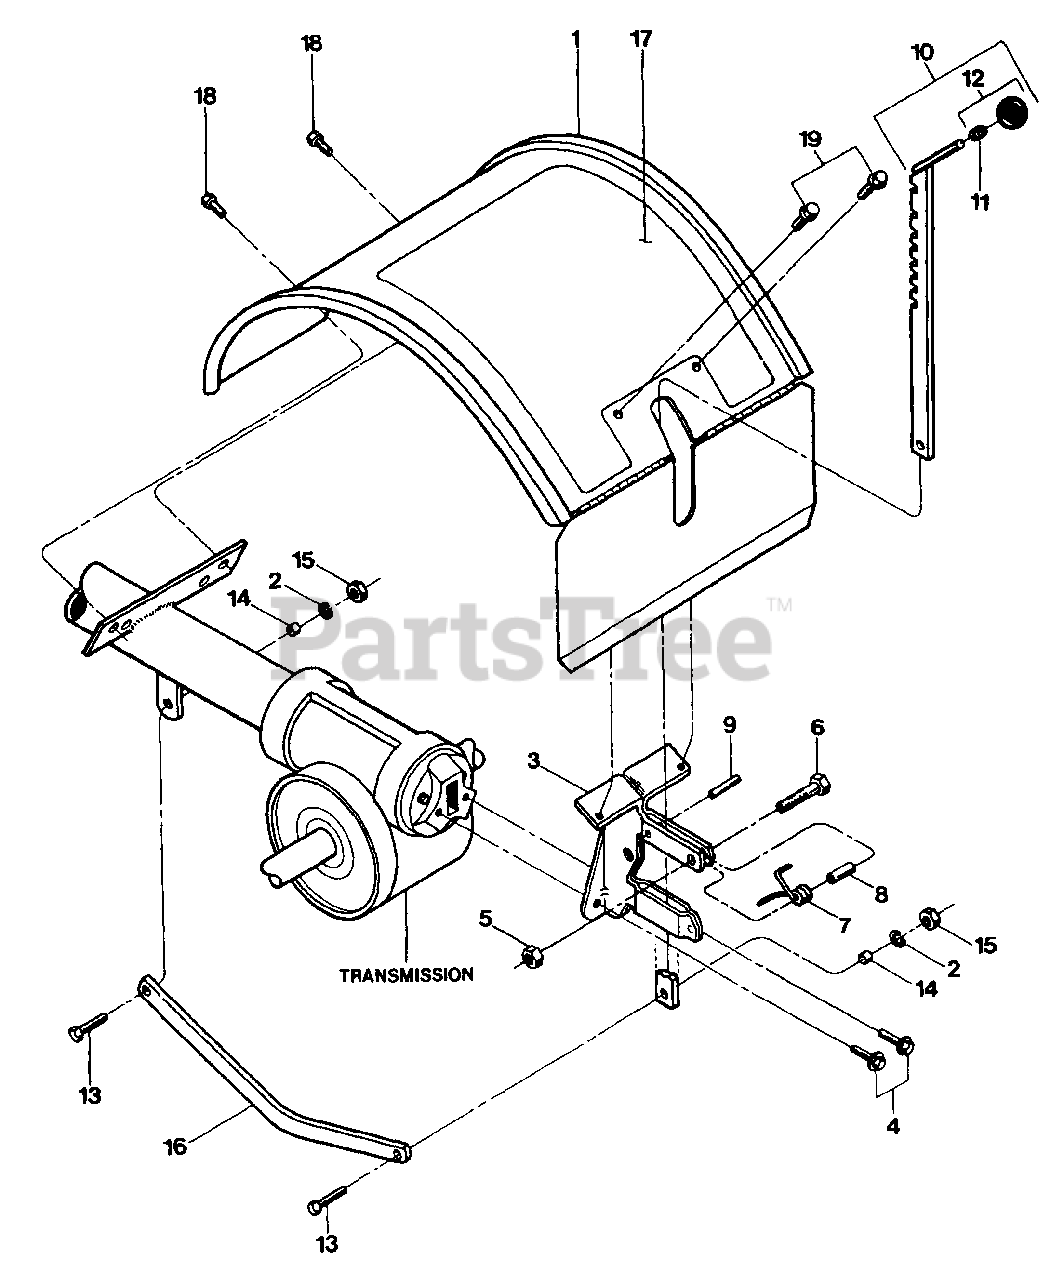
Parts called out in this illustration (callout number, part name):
1	Hood-tine cover, with hinged flap
2	Lockwasher-3/8
3	Bracket-hood & depth regulator
4	Screw-flanged hex hd., 5/16-18 x 5/8
5	Locknut-hex, 1/4-20
6	Screw-hex hd., 1/4-20 x 1
7	Spring-depth regulator plunger
9	Roll Pin-1/4 x 1 (spiral)
10	Bar Assembly-depth adjustment
11	Ring-retaining, tolerance ring
12	Knob-depth regulator
13	Screw-hex hd, 3/8-16 x 1-1/4
14	Bushing-spacer, drag bar
15	Nut-hex, 3/8-16
16	Drag Bar-depth regulator
17	Decal-tiller operating instructions
18	Screw-hex hd, self-tapping, 5/16-18 x 1/2
19	Screw-flanged hex hd, self-tapping, 1/4-20 x 1/2
